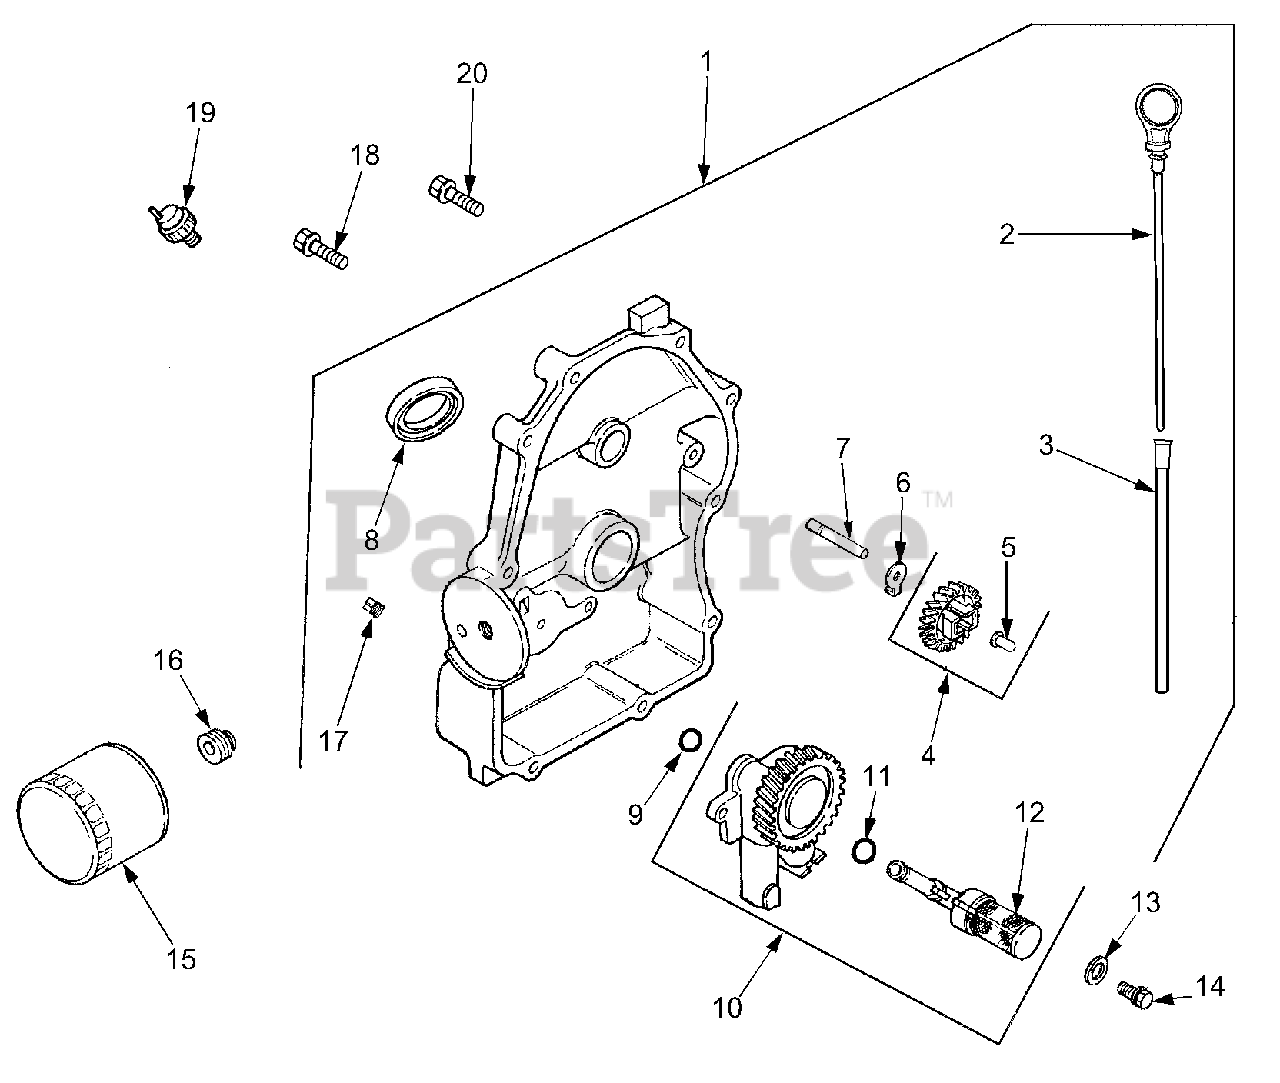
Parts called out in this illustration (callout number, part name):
1	Plate, Closure Assembly
3	Tube, Dipstick
4	Kit, Governor Gear
5	Pin, Governor Regulating
6	Tab, Locking
7	Shaft, Governor Gear
8	Seal, Oil (PTO End)
10	Oil Pump Assembly
11	O-Ring, Oil Pick-Up
12	Pick-Up, Oil
13	Washer, Plain
14	Screw, Hex Flange M6 x 1 x 25
15	Filter, Oil
16	Nipple, Oil Filter
17	Plug, Pipe 1/8"
18	Screw, Hex Flange M8 x 1.25 x 45
19	Switch, Pressure
20	Screw, Hex Flange M8 x 1.25 x 45
